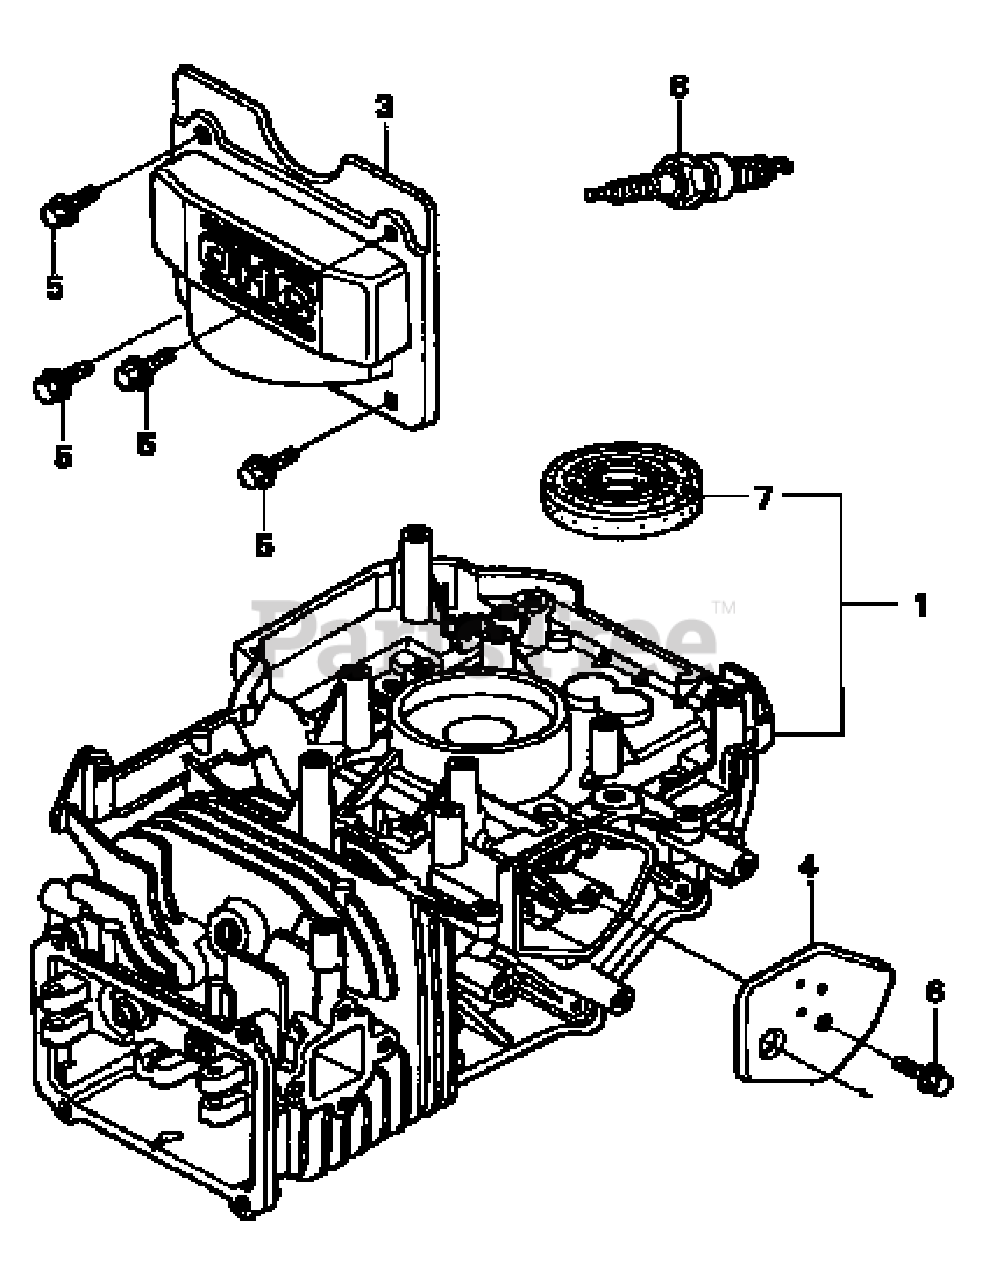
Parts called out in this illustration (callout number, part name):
1	Cylinder Assy.
3	Head Cover
4	Breather Cover
5	Flange Bolt (6x12)
6	Flange Bolt (6x14)
8	Spark Plug
